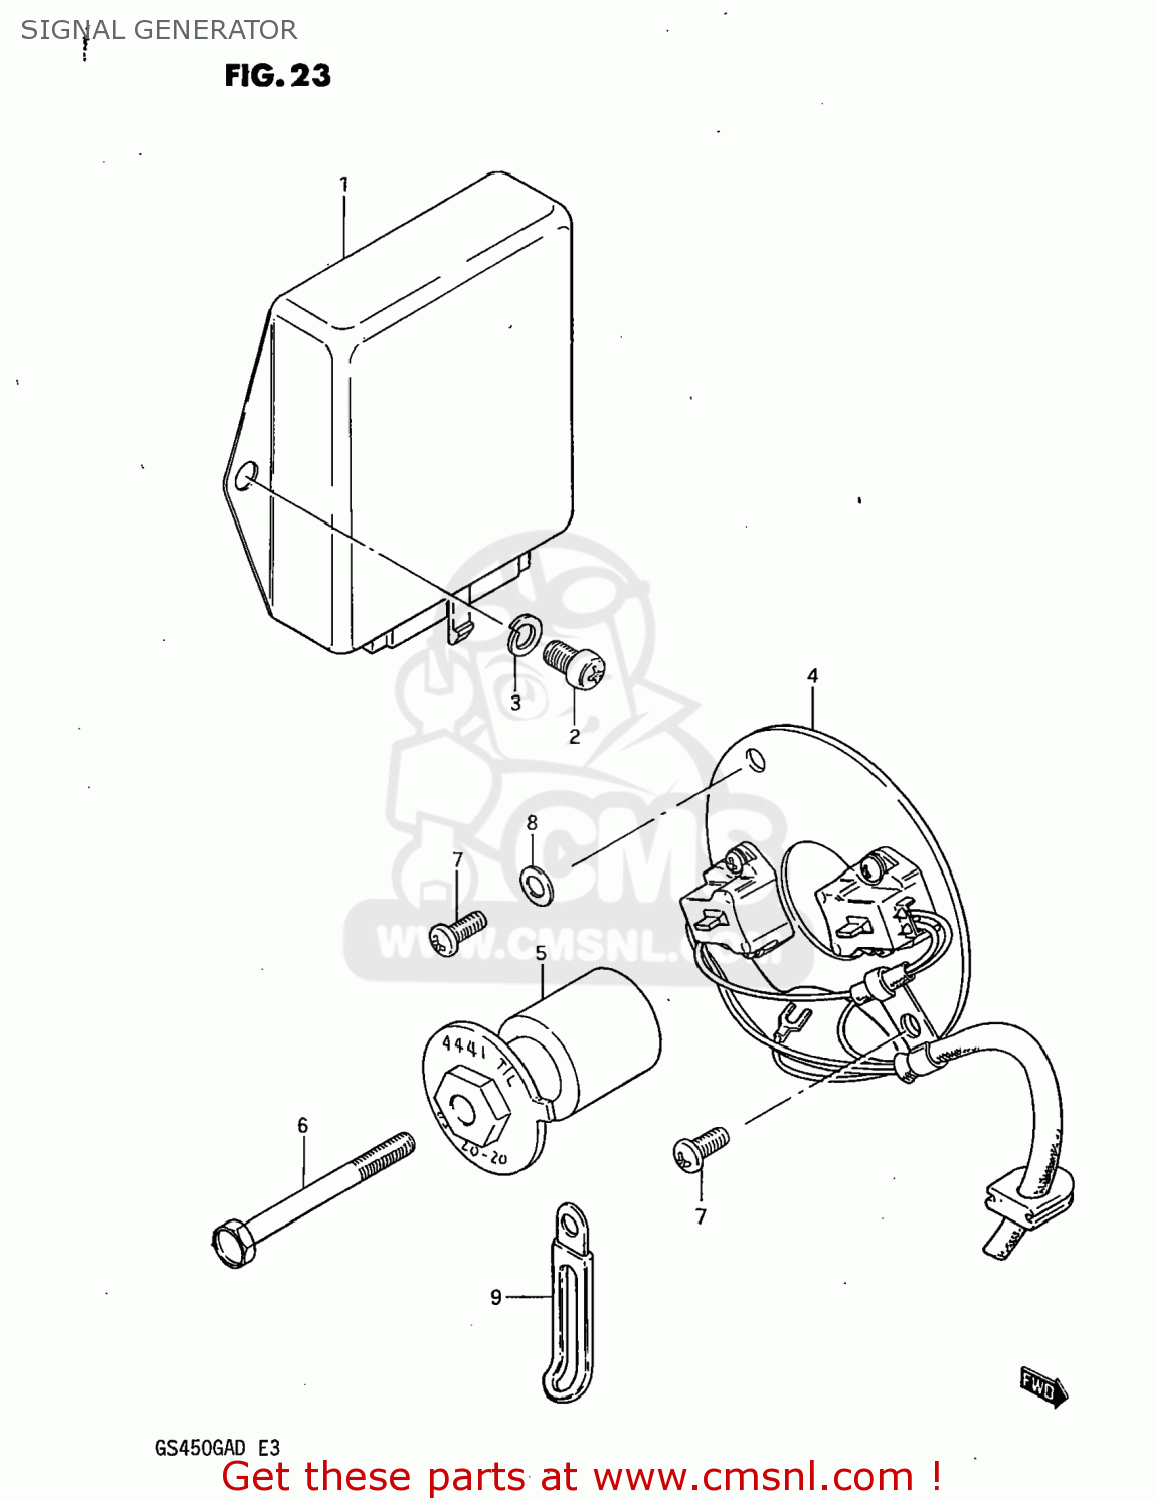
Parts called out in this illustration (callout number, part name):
1	IGNITOR UNIT
2	SCREW
3	LOCK WASHER
4	SIGNAL GENERATOR ASSEMBLY
5	GOVERNOR ASSEMBLY
6	BOLT
7	SCREW(5X12)
8	WASHER
9	CLAMP L:35
